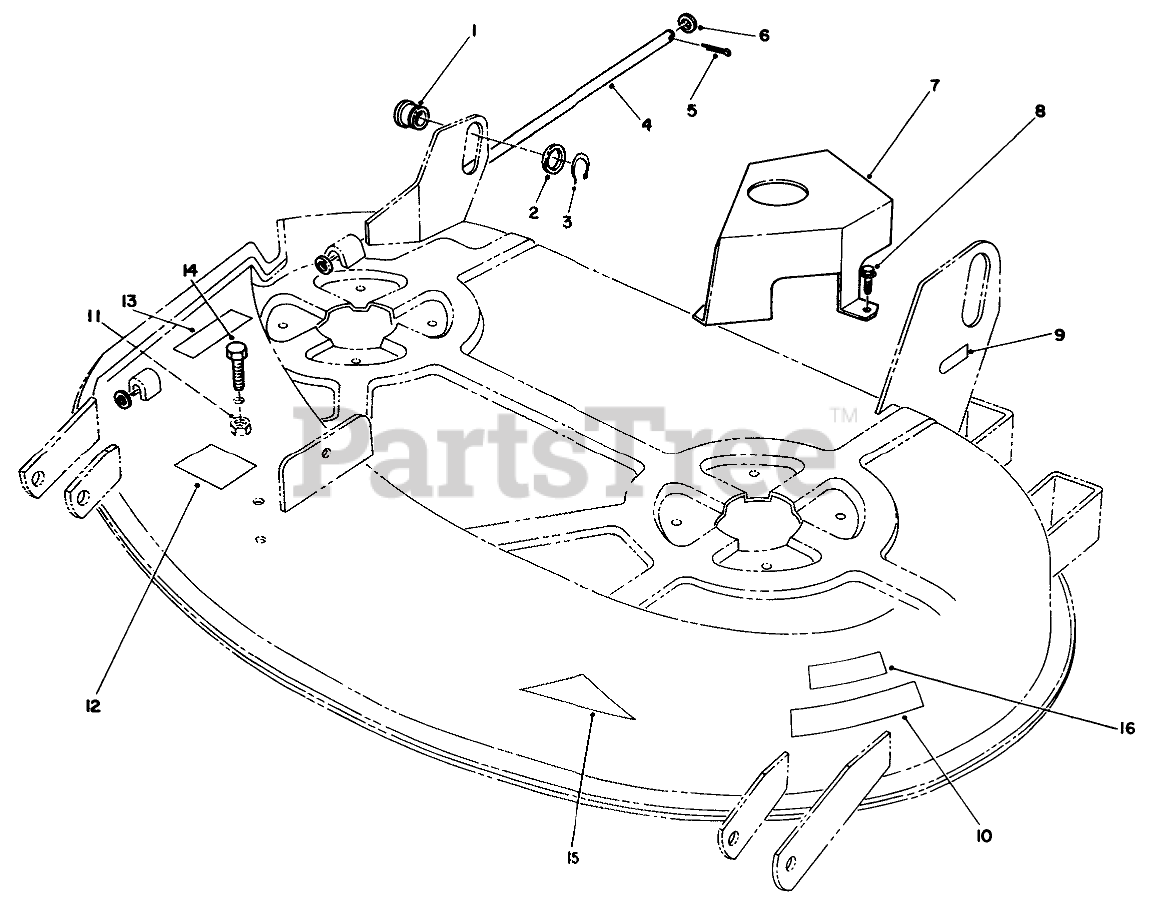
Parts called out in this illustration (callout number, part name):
1	ROLLER-LIFT
2	Washer
3	Snap Ring
5	Cotter Pin
6	WASHER 5/16 SAE
7	Cover-Belt
8	SCREW-HWHTF
9	Decal-Attach-A-Matic
10	DECAL - DANGER
11	Nut
12	Decal-Routing
13	DECAL-DANGER
14	H H C S
15	Decal-OPEI
16	DECAL-OVERLAY
